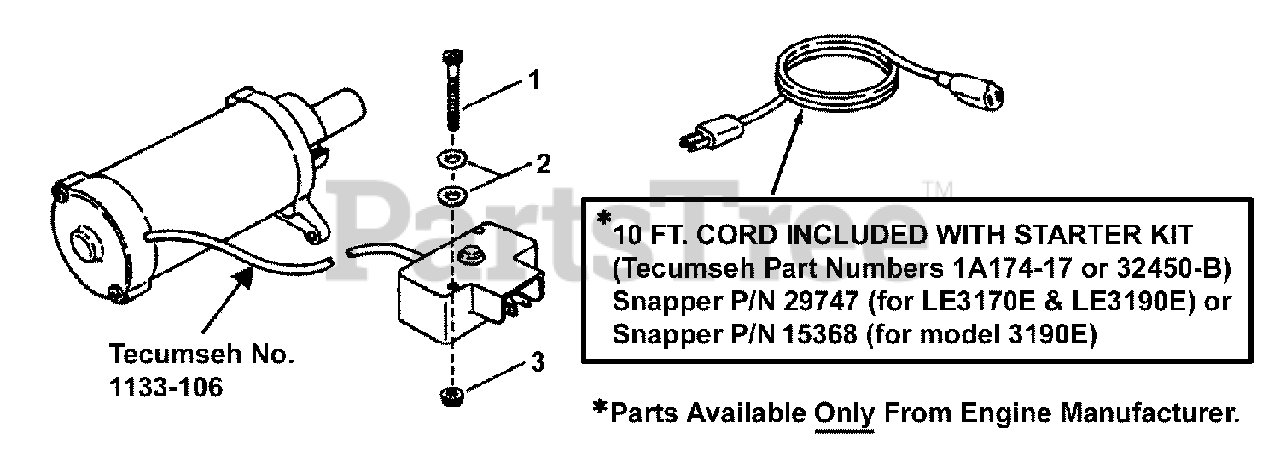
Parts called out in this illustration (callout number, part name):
1	SCREW, 5/16-18 x 3/4" Hex Head Cap GR5
2	BOLT, 5/16-18 x 1-1/4" Sq. Neck Carriage GR5
3	NUT, 5/16-18 Hex Flange Lock GR5
4	SCREW, #8-32 x 1/2" Pan Head Cross Recess
5	BOLT, 5/16-18 x 3/4" Sq. Neck Carriage GR5
6	NUT, #8-32 Hex w/External Tooth Washer
